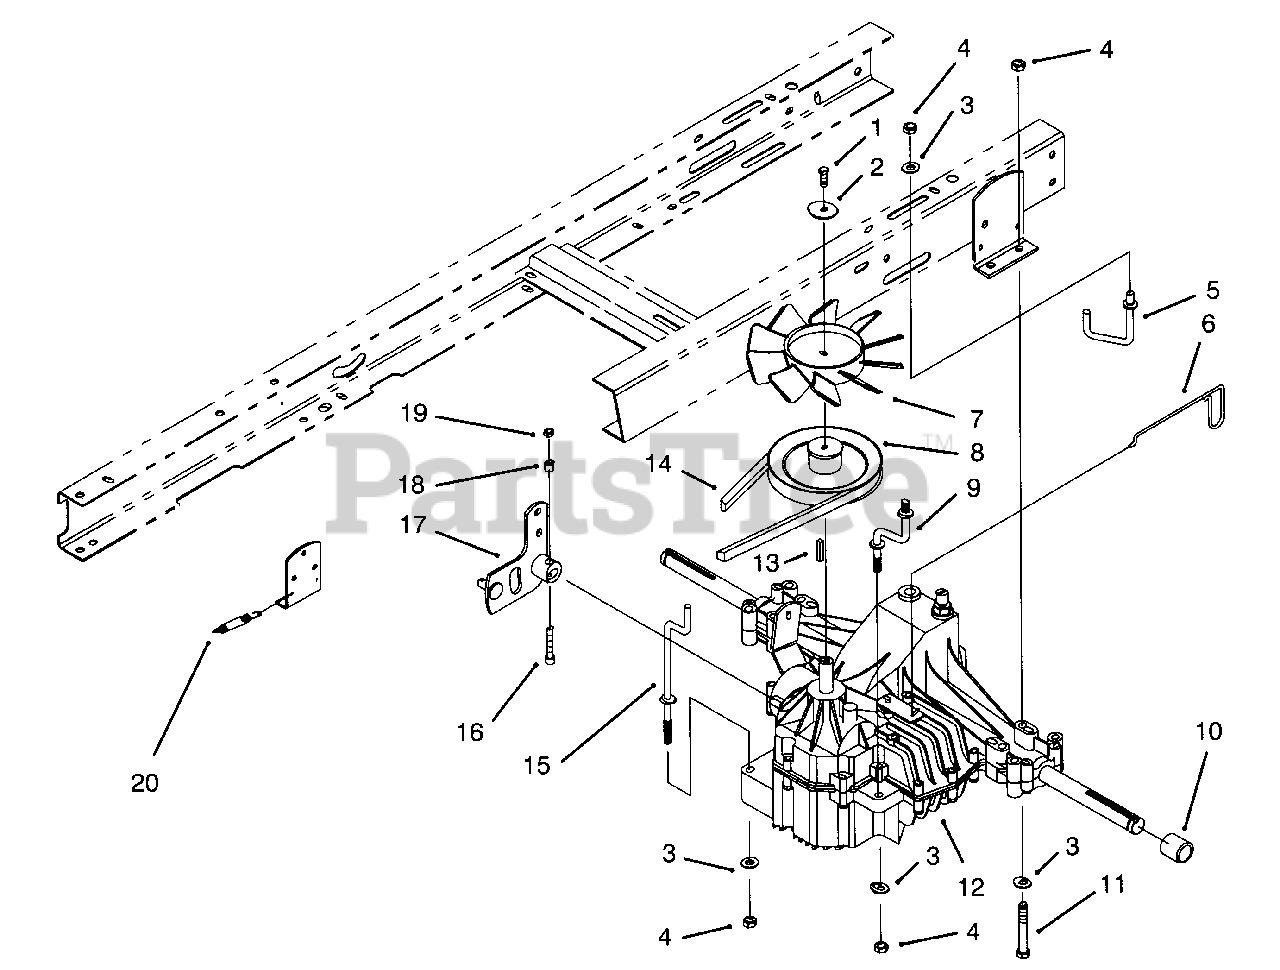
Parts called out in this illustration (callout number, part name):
1	Screw-Hex Hd. Cap
2	Washer-Flat
3	Washer-Flat
4	Nut-Lock
5	Guide-Trans. Belt L.H.
6	Rod-Dump Valve
7	Fan-Hydro
8	Pulley-Transaxle
9	Strap-Torque
10	Spacer-Wheel
11	Screw-Hex Hd. Cap
12	Transaxle
13	Key-Square
14	V-Belt-Transaxle
15	Guide-Trans. Belt R.H.
16	Screw-Hex Hd. Cap
17	Lever-Speed Control
19	Nut-Lock
20	Spring-Brake Return
